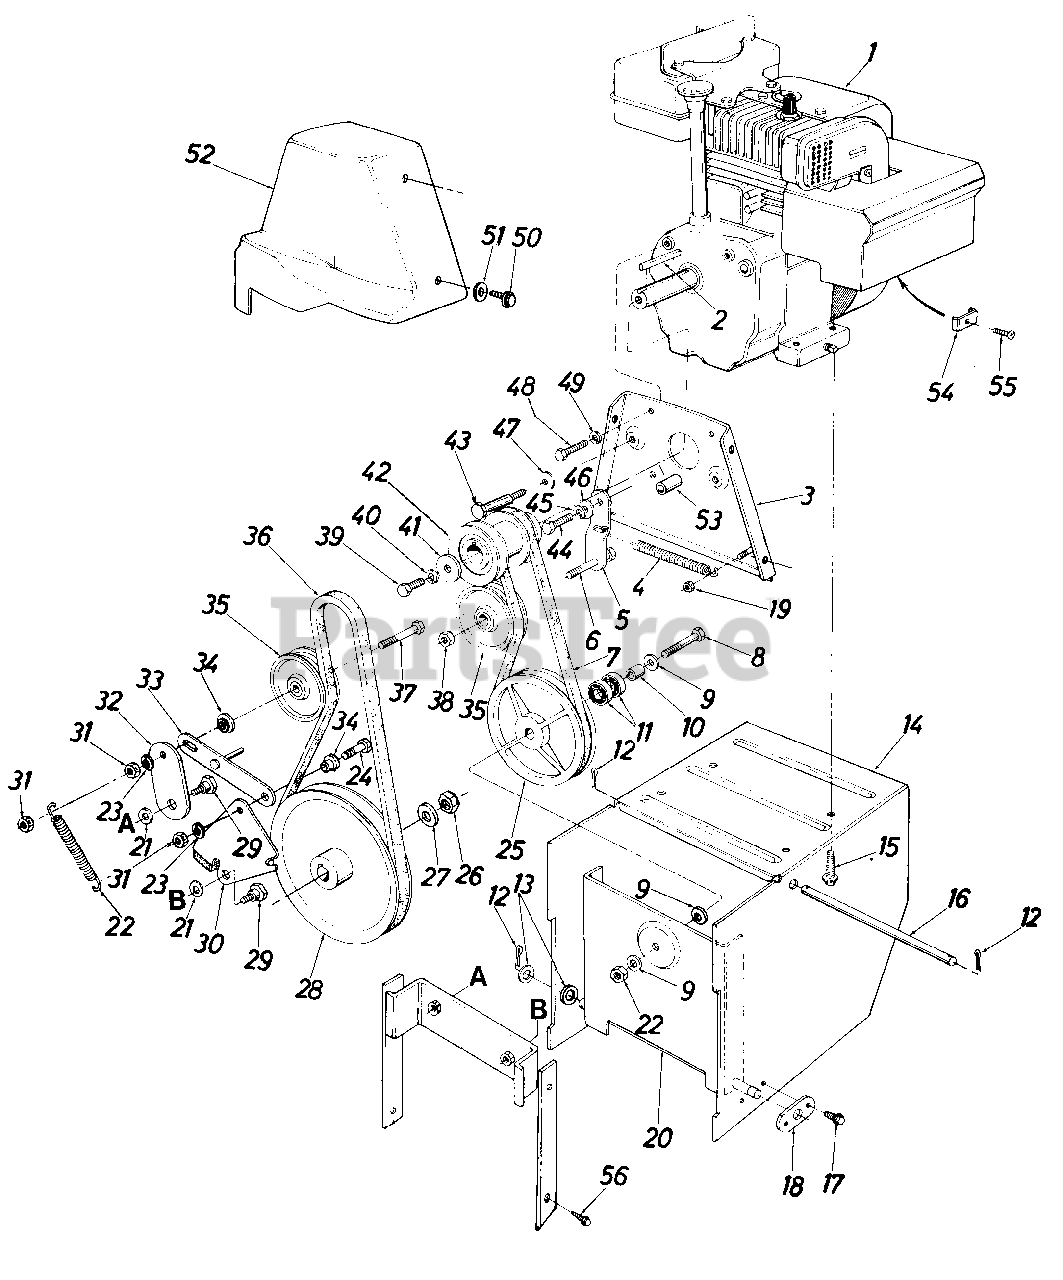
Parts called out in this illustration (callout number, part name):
1	Engine
2	Sq. Key 3/16" x 1.50" Lg.
3	Engine Plate Ass'y.
4	Extension Spring .50" O.D. x 4.25" Lg.
5	Drive Clutch Idler Brk't.
6	Hex Bolt 3/8-24 x 1.25" Lg.*
7	"V"-Belt 3/8" x 29.0" Lg.
8	Hex Bolt 3/8-24 x 1.50" Lg.
9	Bell-Wash. .40" I.D. x .88" O.D. x .06
10	Spacer .38" I.D. x .62" O.D. x .75" Lg.
11	Ball Brg. .62" I.D. x 1.38" O.D. x .44
12	Cotter Pin 3132" Dia. x .75" Lg.*
13	Fl-Wash. .53" I.D. x 1.00" O.D. x .125
14	Frame Ass'y.
15	Hex Wash. Hd. Self-Tap Scr. 3/8-16 x 1.25" Lg.
16	Shaft .50" Dia. x 9.50" Lg.
17	Hex Wash. Hd. Self-Tap Scr. 1/4-20 x .50" Lg.
18	Axle Bracket
19	Hex L-Nut 1/4-20 Thd.
20	Drive Pulley Support Brk't. Ass 'y.
21	Bell-Wash. .40" I.D. x 1.13" O.D.
22	Extension Spring .50" O.D. x 3.97" Lg.
23	L-Wash. 3/8" I.D.
24	Hex Scr. 3/8-16 x 1.25" Lg.
25	6.00" O.D. Drive Pulley Ass'y.
26	Hex Jam Cent. L-Nut 5/8-18 Thd.
27	Fl-Wash. .64" I.D. x .94" O.D. x .06
28	1/2" V-Pulley .625" I.D. x 7.50" O.D.
29	Shld. Bolt .625" Dia. x .170" Lg. (3/8-16)
30	Brake Bracket Ass'y.
31	Hex Ins. L-Nut 3/8-16 Thd.
32	Auger Clutch Idler Brk't.
33	Brake Linkage Ass'y.
34	Shld. Spacer.625" I.D.
35	Flat Id ler 2.25" O.D.
36	"V"-Belt 3/8 x 38" Lg.
37	Hex Bolt 3/8-16 x 2.25" Lg.*
38	Hex Ins. Jam L-Nut 3/8-24 Thd.
39	Hex Bolt 3/8-24 x 1.50" Lg.
40	L-Wash. 3/8 I.D.*
41	Fl-Wash. .40" I.D. x 1.25" O.D.
42	Double Groove Engine Pulley
43	Shld. Scr. .498" x 3.0" Lg.
44	Hex Bolt 5/16-24 x 1.00" Lg.*
45	L-Wash. 5/16" I.D.*
46	Shld. Spacer.320" I.D.
47	Bell-Wash. .40" I.D. x .88" x .06
48	Hex Bolt 5/16-24 x .62" Lg.*
49	L-Wash. 5/16" I.D.*
50	Hex Wash. Hd. Self-Tap Scr. 1/4-20 x .50" Lg.
51	Fl-Wash. .28" I.D. x .75" O.D. x .06
52	Belt Cover
54	Throttle Control Wire Clamp
55	Hex Sems Scr. #10-32 x .62"
56	Hex Wash. Hd. Self-Tap Scr. 3/8-16 x .75" Lg.
